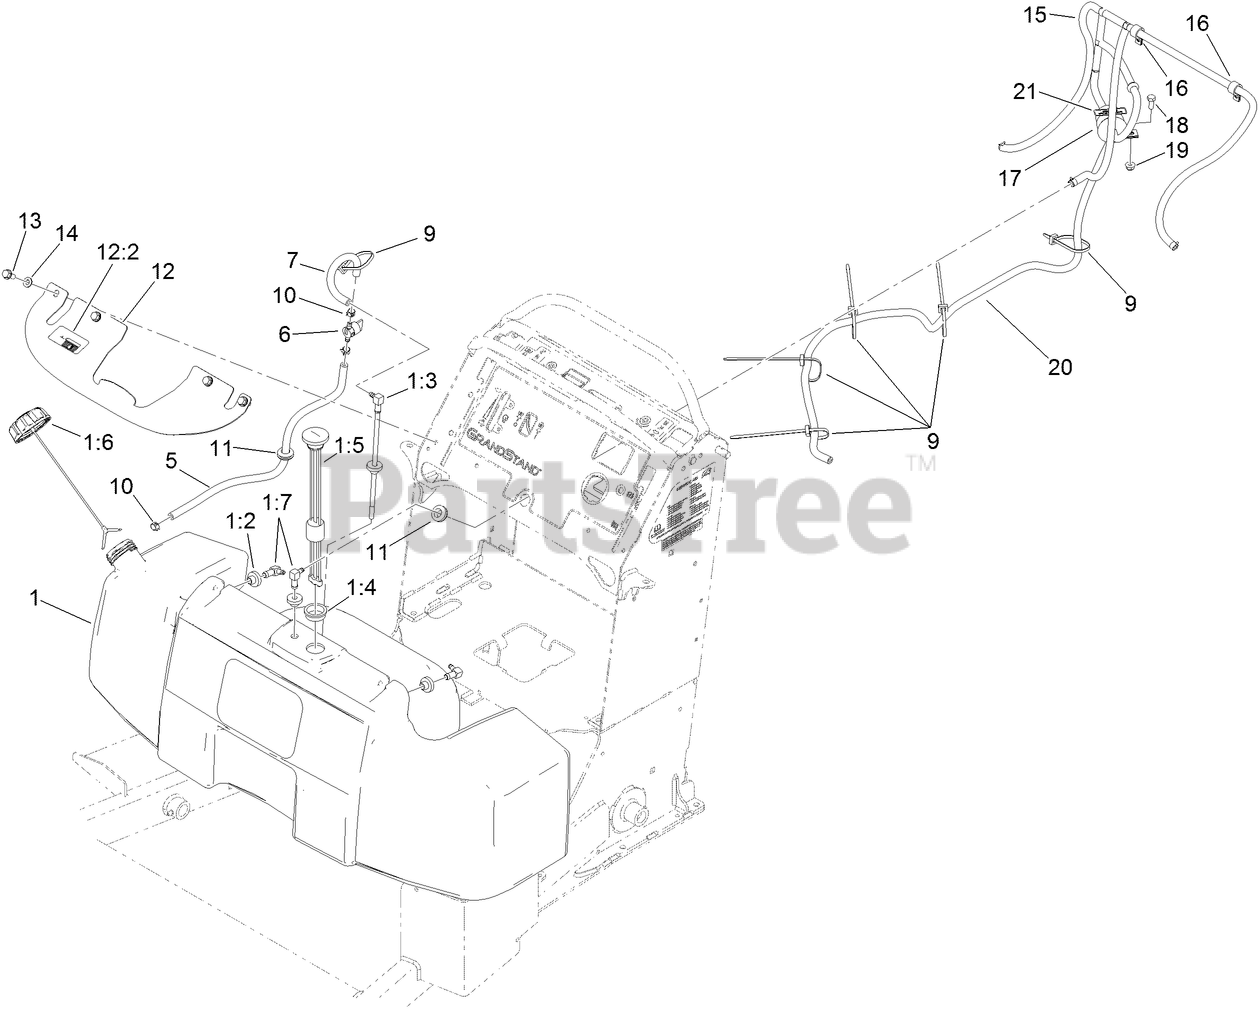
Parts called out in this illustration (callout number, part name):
1	TANK ASM
1:2	BUSHING
1:3	FITTING-FUEL, SCREEN TUBE
1:4	GROMMET
1:5	GUAGE-FUEL
1:6	CAP-FUEL, RATCHETING
1:7	ELBOW-90 DEG
5	HOSE-FUEL
6	VALVE-FUEL
7	HOSE-FUEL
9	TIE-CABLE
10	CLAMP-HOSE
11	GROMMET
12	BRACKET-TANK
12:2	DECAL-FILL, FUEL
13	SCREW-HWHTF
14	WASHER-FLAT
15	VENT HOSE ASM
16	CLAMP-CABLE
17	CLAMP-R
18	SCREW-HH
19	NUT-HF, NI
20	HOSE-FUEL
21	DECAL-FILTER, EMISSIONS
